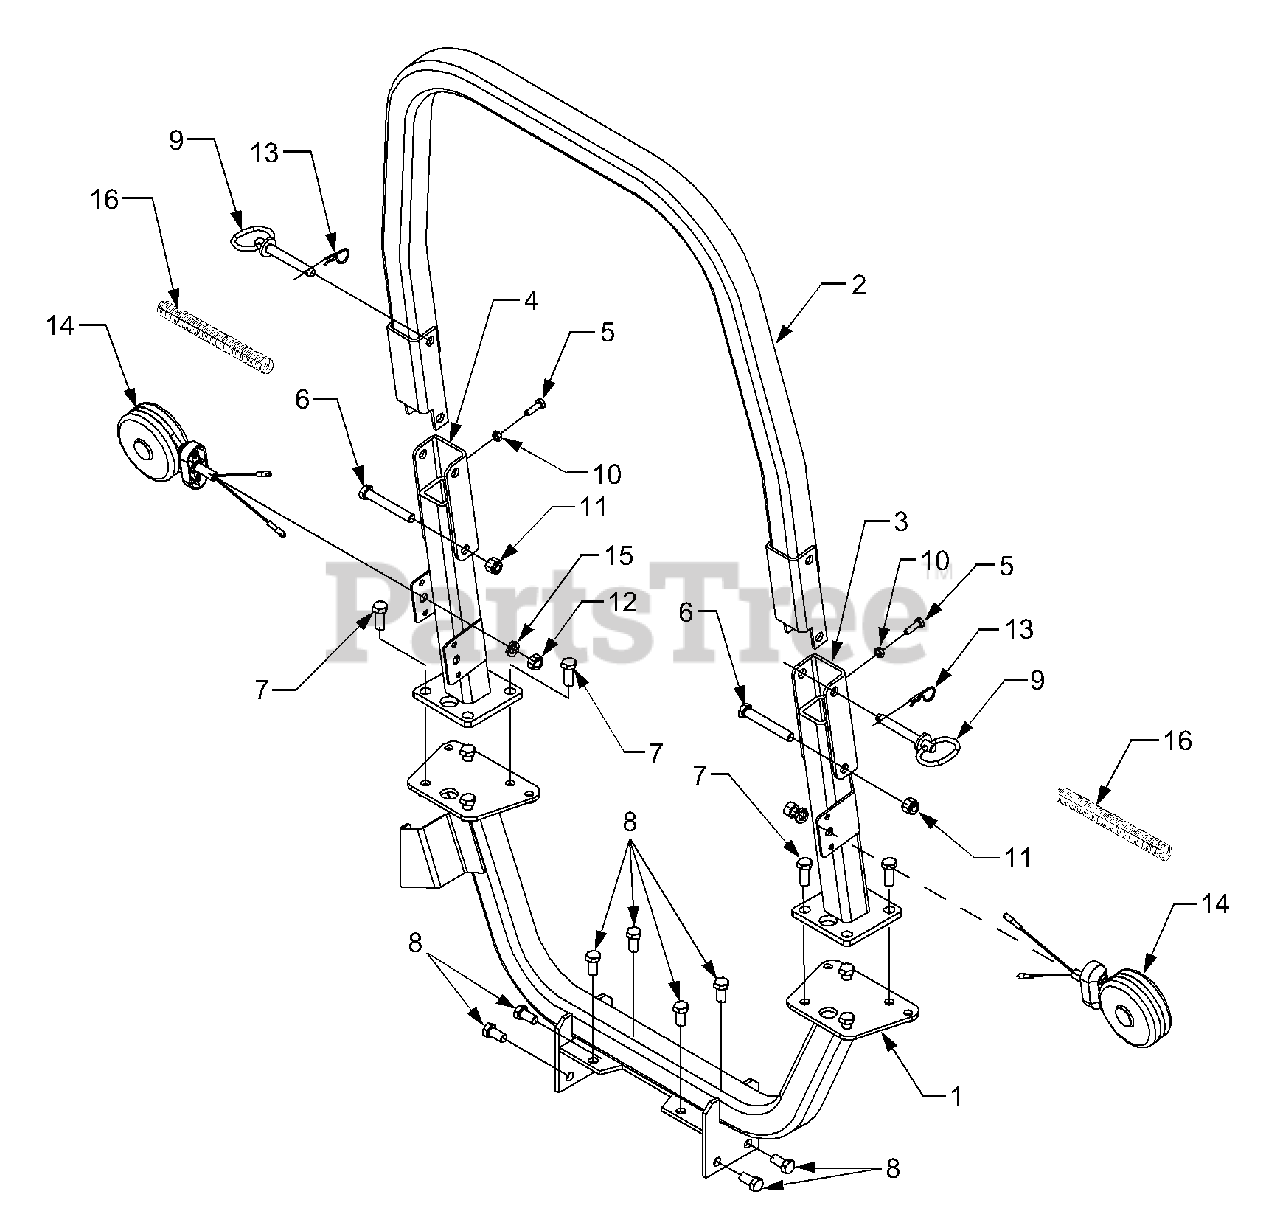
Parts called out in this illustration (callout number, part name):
1	ROPS Assembly, Lower
2	ROPS Assembly, Upper
3	Mounting Assembly, ROPS RH
4	Mounting Assembly, ROPS LH
5	Screw, Hex Cap, 5/16-18 x 1.0 GR5
6	Screw, Hex Cap, 1/2-20 x 3.5 GR5
7	Screw, Hex Cap, 1/2-13 x 1.25 GR5
8	Screw, Hex Cap, 1/2-13 x 1.0 GR5
9	Pin, Clevis, .5 x 3.5
10	Nut, Hex Jam, 5/16-18
11	Nut, Hex Nylon Insert Lock, 1/2-20
12	Nut, Hex, 1/2-20 GR5
13	Pin, Internal Cotter
14	Light Assembly, Hazard
15	Washer, Lock, 1/2
